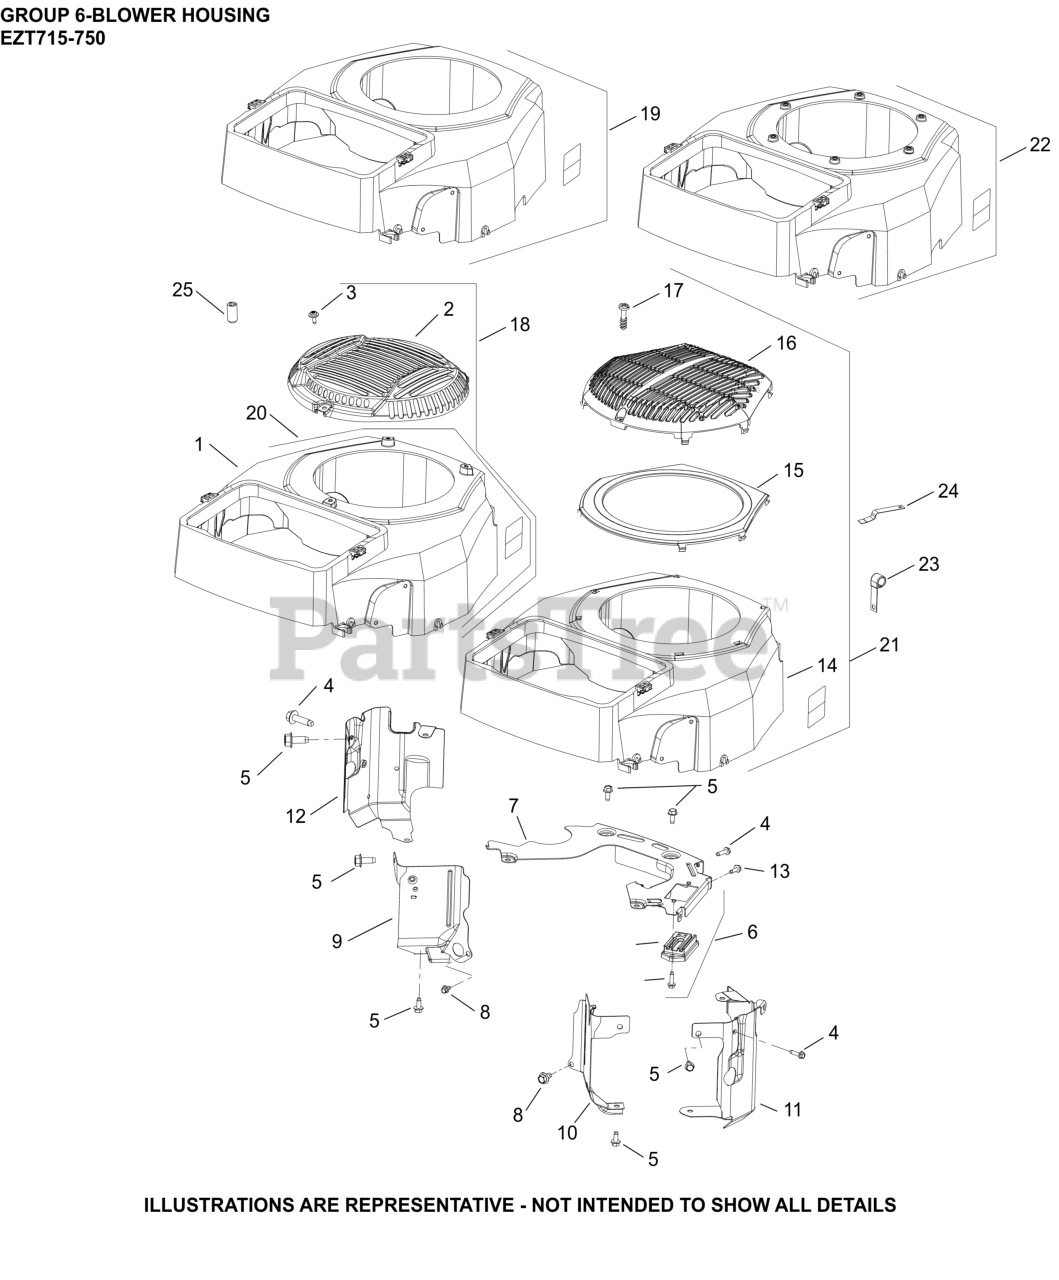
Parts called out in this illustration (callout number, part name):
4	SCREW, THD FRM-USE 25 086 473-S
5	SCREW, THREAD FORMING
6	PLATE ASSEMBLY, BACKING (15A)
7	PLATE, BACKING
8	SCREW, THREAD FORMING
9	BAFFLE, VALLEY #1
10	BAFFLE, VALLEY #2
11	BAFFLE, LEFT BARREL
12	BAFFLE, RIGHT BARREL
13	SCREW, THREAD FORMING
14	KIT, BLOWER HOUSING-USE 16 027 11-S
16	GUARD, FIXED
17	SCREW, M5-2.42 (PT) THREAD
